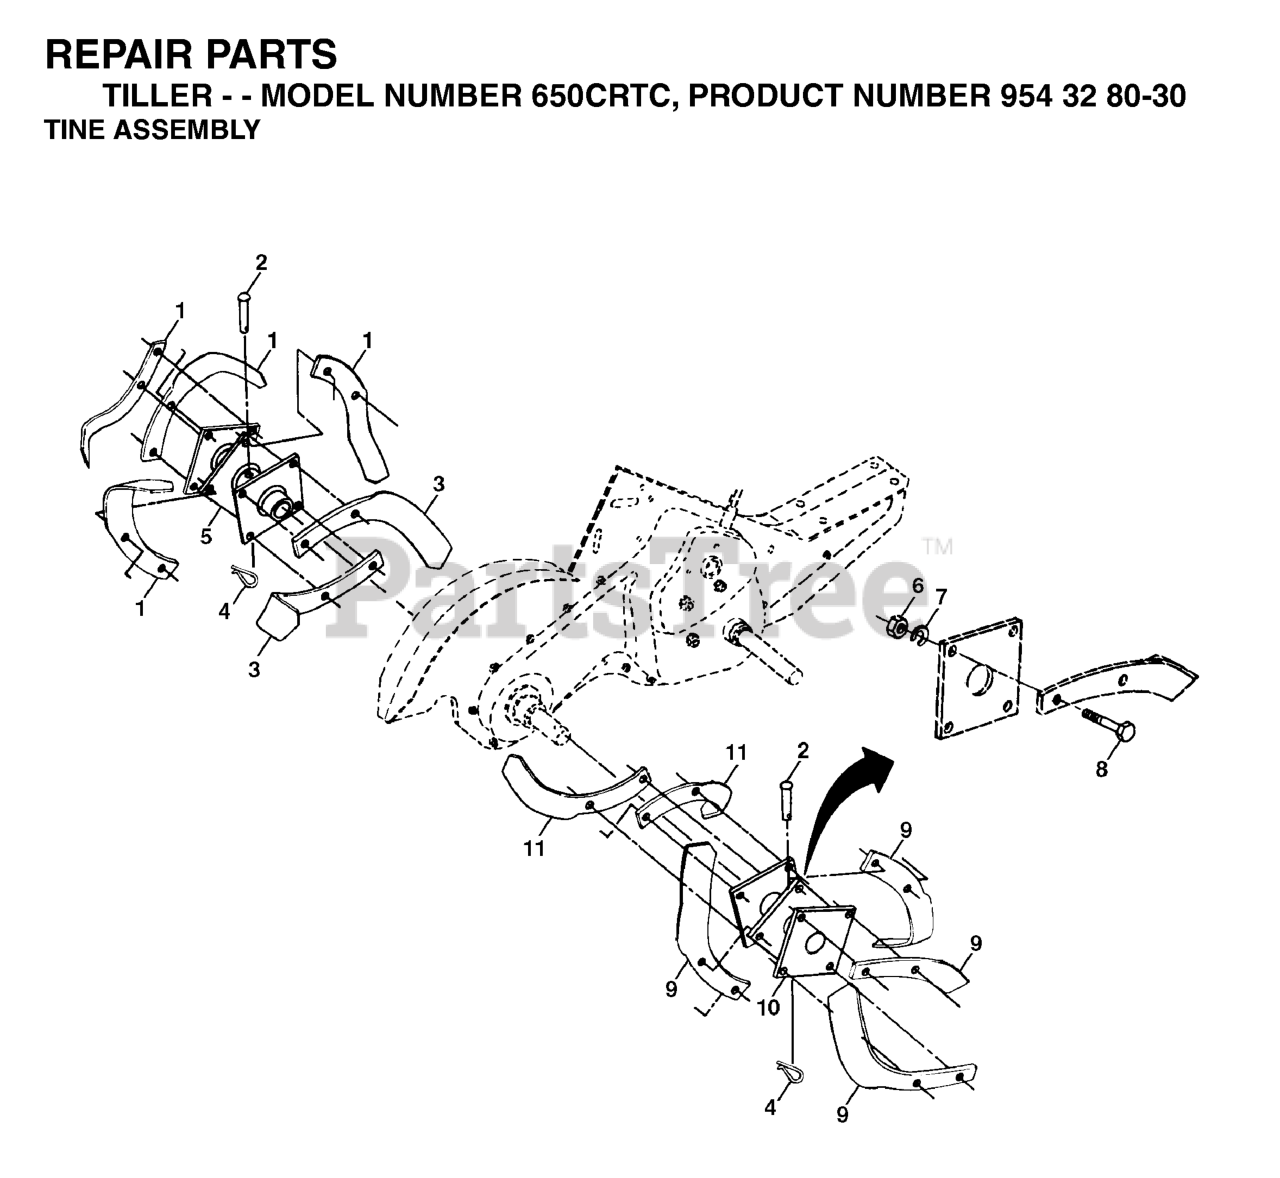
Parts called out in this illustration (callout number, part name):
1	TINE TI
2	PIN RETAINING SCREW
3	TINE.LH.12"(72L)
4	SPRING RETAINER
5	HUB.&.PLATE.ASM.LH
6	NUT
7	WASHER, LOCK 3/8
8	BOLT.HEX.001X20.37-24X1.ZINC
9	TINE TI
10	HUB & PLATE ASM RH
11	TINE.RH.12"(72R)
